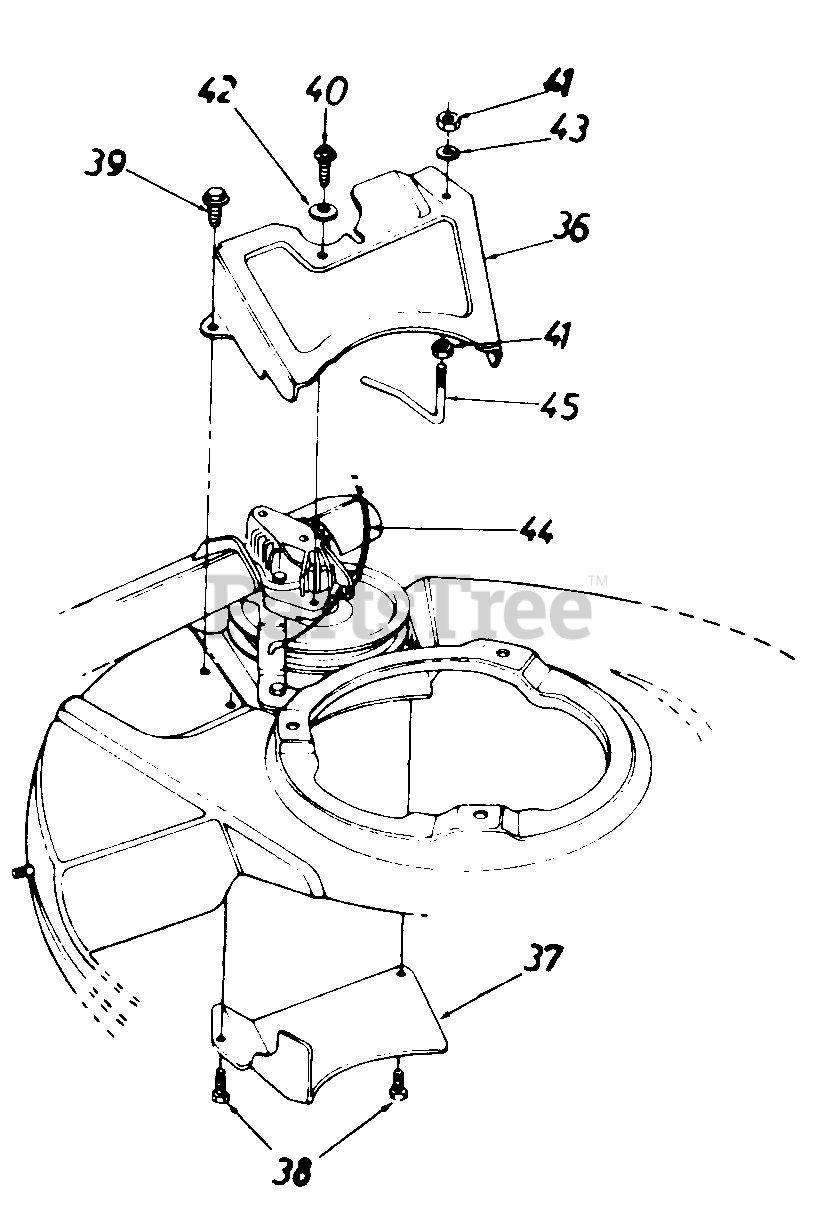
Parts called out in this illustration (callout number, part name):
39	Hex AB-Tap Scr. 1/4 x .50" Lg.
40	Hex B-Tap Scr. 1/4 x .62" Lg.
41	Hex Nut 1/4-20 Thd.
42	Bell-Wash. .265" I.D. x 75"
43	L-Wash. 1/4" I.D.
44	S.P. Cable--48" Lg.
45	S.P. Belt Guard
